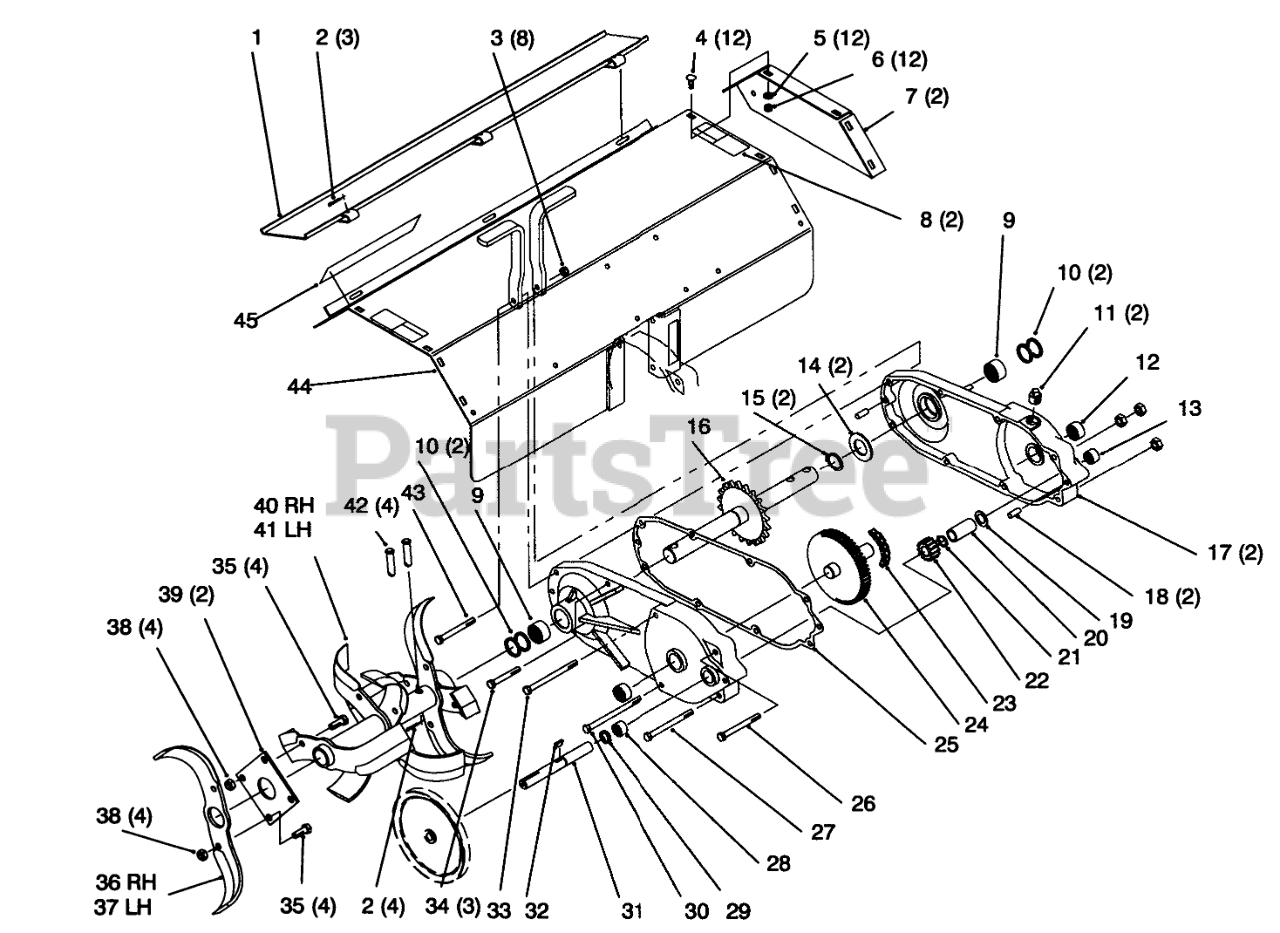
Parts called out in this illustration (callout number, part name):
1	GUARD ASM
2	PIN-COTTER
3	NUT-LOCK, NI
4	BOLT-CARR
5	WASHER-PLAIN
6	NUT-LOCK, NI
7	COVER-TINE END
8	DECAL-DANGER
9	BEARING-NEEDLE
11	PLUG-PIPE, SQH
12	BEARING-NEEDLE
13	BEARING-NEEDLE
14	WASHER
15	RING-RETAINING
16	TINE SHAFT ASM
17	GEAR CASE TILLER RED
18	PIN-ROLL
19	WASHER-THRUST
20	TUBE-SPACER
21	Ring-Snap
22	GEAR-PINION
23	CHAIN
24	GEAR AND SHAFT ASM
25	GASKET-TRANSMISSION
26	SCREW-HH
27	SCREW-HH
28	BEARING-NEEDLE
29	SEAL-OIL
30	SCREW-HH
31	SHAFT-INPUT
32	KEY-WOODRUFF
33	SCREW-HH
34	SCREW-HH
35	SCREW-HH
36	TINE-RH
37	TINE-LH
38	NUT-LOCK, NI
39	PLATE-TINE MTG RED
40	RH TINE ASM
41	LH TINE ASM
42	PIN-CLEVIS
43	SCREW-HH
44	Shield W/Safety Decal
45	DECAL-ATTACHMENT
